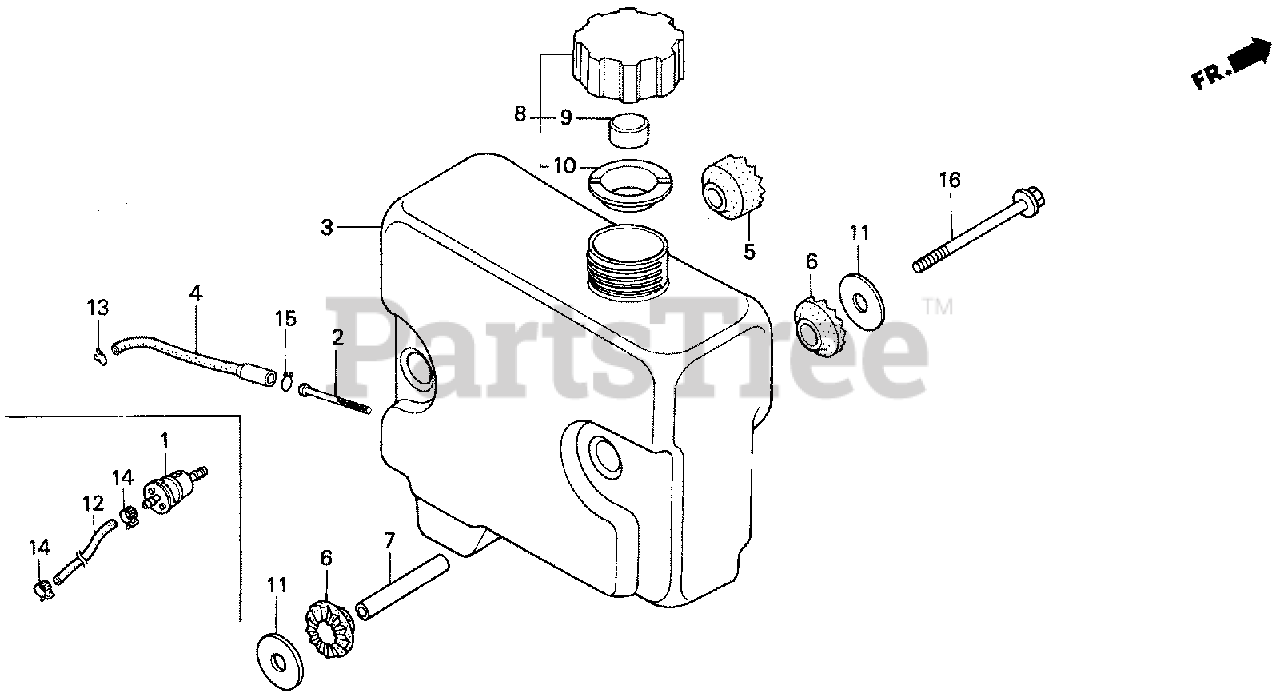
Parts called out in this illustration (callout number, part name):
1	FILTER, FUEL
12	BULK HOSE, FUEL (4.5X3000) (Honda Code 2380558). (4.5X360)
14	CLIP, TUBE (D8.5)
